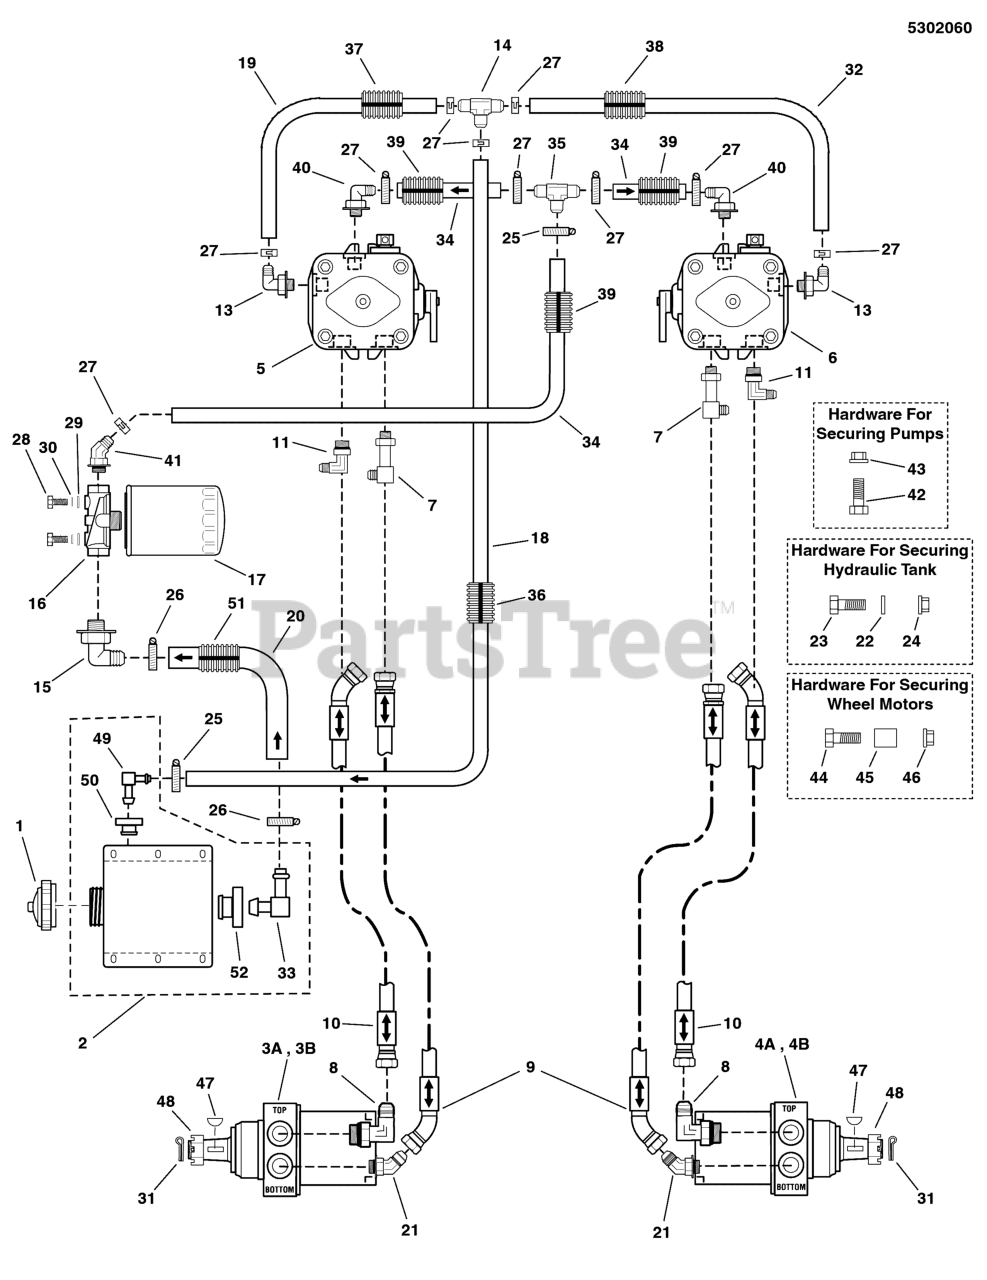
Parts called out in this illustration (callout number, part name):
1	CAP, HYDRAULIC, SHIELDED VENT
2	TANK, HYDRAULIC, ASSEMBLY
5	PUMP, HYD, 12CC - LH, PK-3HBQ-FV1F-XXXX
6	PUMP, HYD, 12CC - RH, PK-3KBQ-FV1F-XXXX
7	FITTING, #8JIC TO #8 O-RING, 90 ELBOW
8	FITTING, #10 ORING-#8 JIC, 90D
9	HOSE ASSEMBLY, (29)
10	HOSE ASSEMBLY, (25.5)
11	FITTING, #8 JIC - #8 O-RING, 90 DEG.
12	FAN SHROUD
13	ADAPTER, 90 DEG, 9/16-3/8 BARB
14	FITTING, TEE, 1/2 HOSE
15	ADAPTER, 90 DEG, 9/16-5/8 BARB
16	FILTER HEAD, HYDRAULIC
17	FILTER, OIL
18	HOSE, 3/8" PUSH-LOCK, 16.00"
19	HOSE, 3/8" PUSH-LOCK, 10.00"
20	HOSE, 5/8 PUSH-LOCK, 20.00
21	FITTING, #8 JIC - #10 O-RING, 45 DEG.
22	WASHER, 5/16" SAE
23	BOLT, 5/16-18 X 1 GD5 YZ
24	NUT, 5/16-18 HEX NYLOCK FLANGE
25	CLAMP, #4 HOSE, STAINLESS
26	CLAMP, #10 HOSE, STAINLESS
27	CLAMP, HOSE
28	BOLT, 1/4-20 X 3/4 GD5 YZ
29	WASHER, 1/4 SAE
30	WASHER, 1/4 LOCK
31	PIN, COTTER, 1/8 X 2
32	HOSE, 3/8 PUSH-LOCK, 26.00
33	FITTING, 90 DEG, 5/8
34	HOSE, 1/2" PUSH-ON, 14.00"
35	FITTING, BEADED TEE, 1/2 X 1/2 X 1/2, YZ
36	WIRE LOOM, 5/8" ID, 14" LONG
37	WIRE LOOM, 5/8" ID, 8" LONG
38	WIRE LOOM, 5/8" ID, 24" LONG
39	WIRE LOOM, 3/4" ID, 12" LONG
40	FITTING, 9/16 O-RING-1/2" HOSE, 90 DEG
41	FITTING, 1/2 HOSE - 9/16 O-RING, 45 ELB
42	BOLT, 7/16-20 X 1-1/4 GD5
43	NUT, 7/16-14 HEX SERRATED FLANGE (SMALL)
44	BOLT, 1/2-13 X 2-1/2, NYLON PATCH
45	SPACER, .53 X 1.00 X 1.00
46	NUT, 1/2-13 SQUARE
47	KEY, WOODRUFF, #1008, 5/16 X 1
48	NUT, CASTLE 1-20
49	FITTING-90 DEG, 3/8
50	BUSHING-FUEL TANK RED RUBBER
51	LOOM, CONVOLUTED SPLIT, 1 ID - 18 LONG
52	GROMMET
